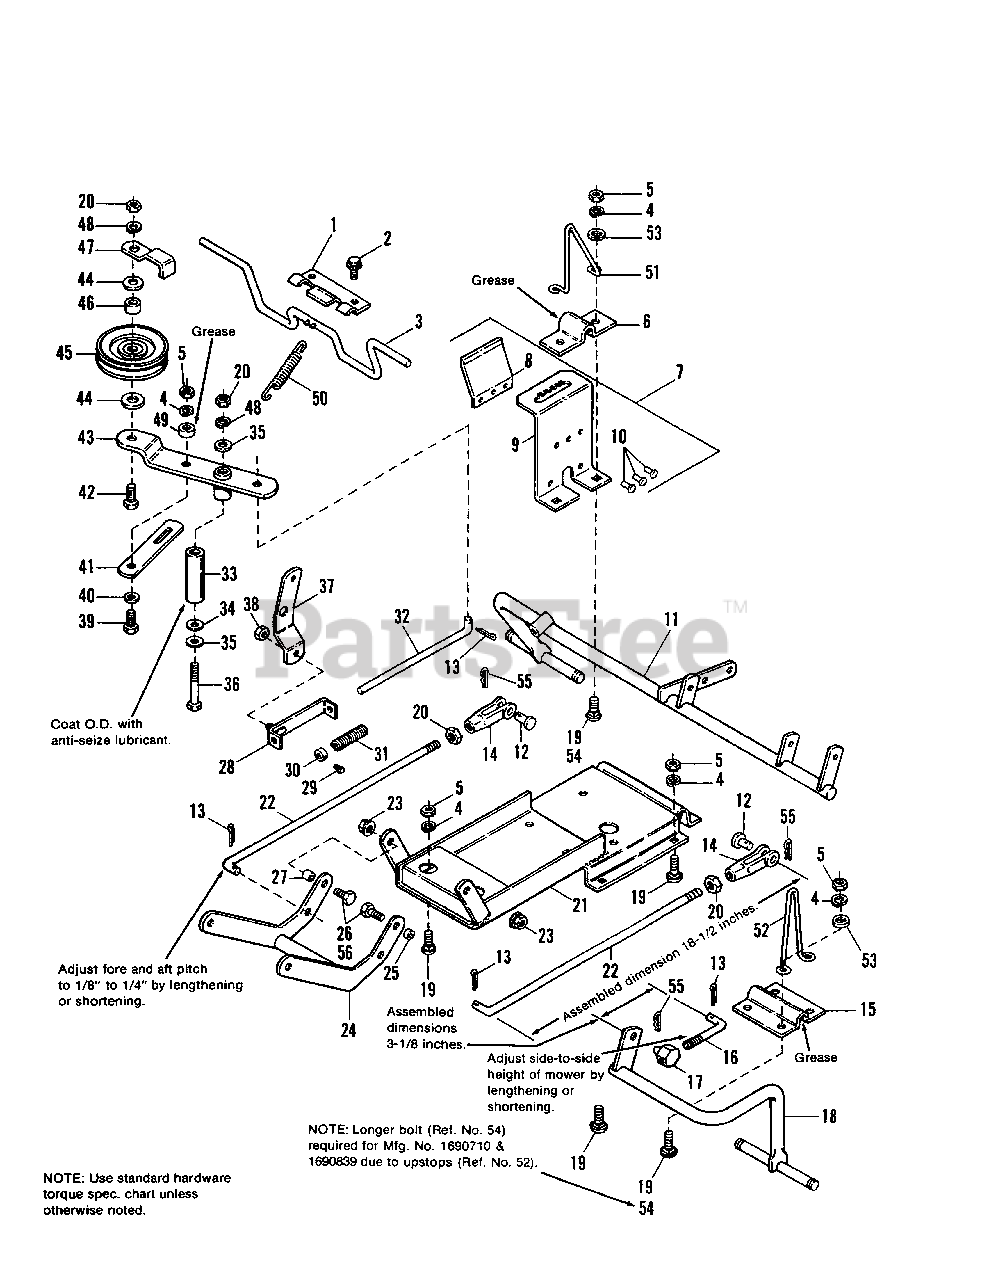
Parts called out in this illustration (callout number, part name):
1	SUPPORT, Brake
2	SCREW, Hex, Washer Hd., Taptite, 1/4-20 x 3/8
3	ROD ASSY., Brake
4	LOCKWASHER, 5/16
5	NUT, Hex, Full, 5/16-18
7	QUADRANT ASSY.
8	SPRING, Flat
10	RIVET, Tubular, 3/16 x 5/16
11	SUPPORT ASSY., Roller, R.H.
12	PIN, Clevis
13	PIN, Cotter, 3/32 x 3/4
14	CLEVIS, Adjusting
15	CLAMP, Wheel Support
18	SUPPORT ASSY., Roller, L.H.
19	BOLT, Carriage, 5/16-18 x 3/4 (Qty. 14 for 1690627)
20	NUT, Hex, Full, 3/8-16 (Qty. 6 on 1690839)
21	SUPPORT ASSY., Mower
21	SUPPORT ASSY., Mower (1690839 after serial no. 1698)
22	ROD, Height Adjustment
23	LOCKNUT, Hex, Flange, 3/8-16
24	ARM ASSY., Rocker (1690627 & 1690710 & 1690839 before serial no. 1699)
24	ARM ASSY., Rocker (1690839 after serial no. 1698)
26	CAPSCREW, Hex Hd., 3/8-16 x 1
28	GUIDE ASSY., Rod
29	SETSCREW, 1/4-20 x 3/8
30	COLLAR, Set
32	ROD, Clutch
35	WASHER, Plain, 3/8
36	CAPSCREW, Hex Hd., 3/8-16 x 2-3/4
37	ARM, Pivot (1690627 only)
37	ARM, Pivot (1690710 & 1690839)
38	LOCKNUT, Hex, 5/16-18
39	CAPSCREW, Hex Hd., 5/16-18 x 1.0
40	WASHER, Plain, 1/4
41	LEVER, Brake
42	CAPSCREW, Hex Hd., 3/8-16 x 1-3/4 (Was 921969, 1-1/2)
43	LEVER ASSY., Clutch
44	WASHER, Plain
45	PULLEY ASSY. (Incl. Ref. No. 46)
47	GUIDE, Belt
48	LOCKWASHER, 3/8
51	UP-STOP, R.H. (Not used on 1690627)
52	UP-STOP, L.H. (Not used on 1690627)
53	WASHER, Plain, 5/16 (Not used on 1690727)
54	BOLT, Carriage, 5/16-18 x 1-1/4 (Not used on 1690627)
55	CLIP, Hairpin
56	CAPSCREW, Hex Hd., 3/8-16 x 1-1/4
